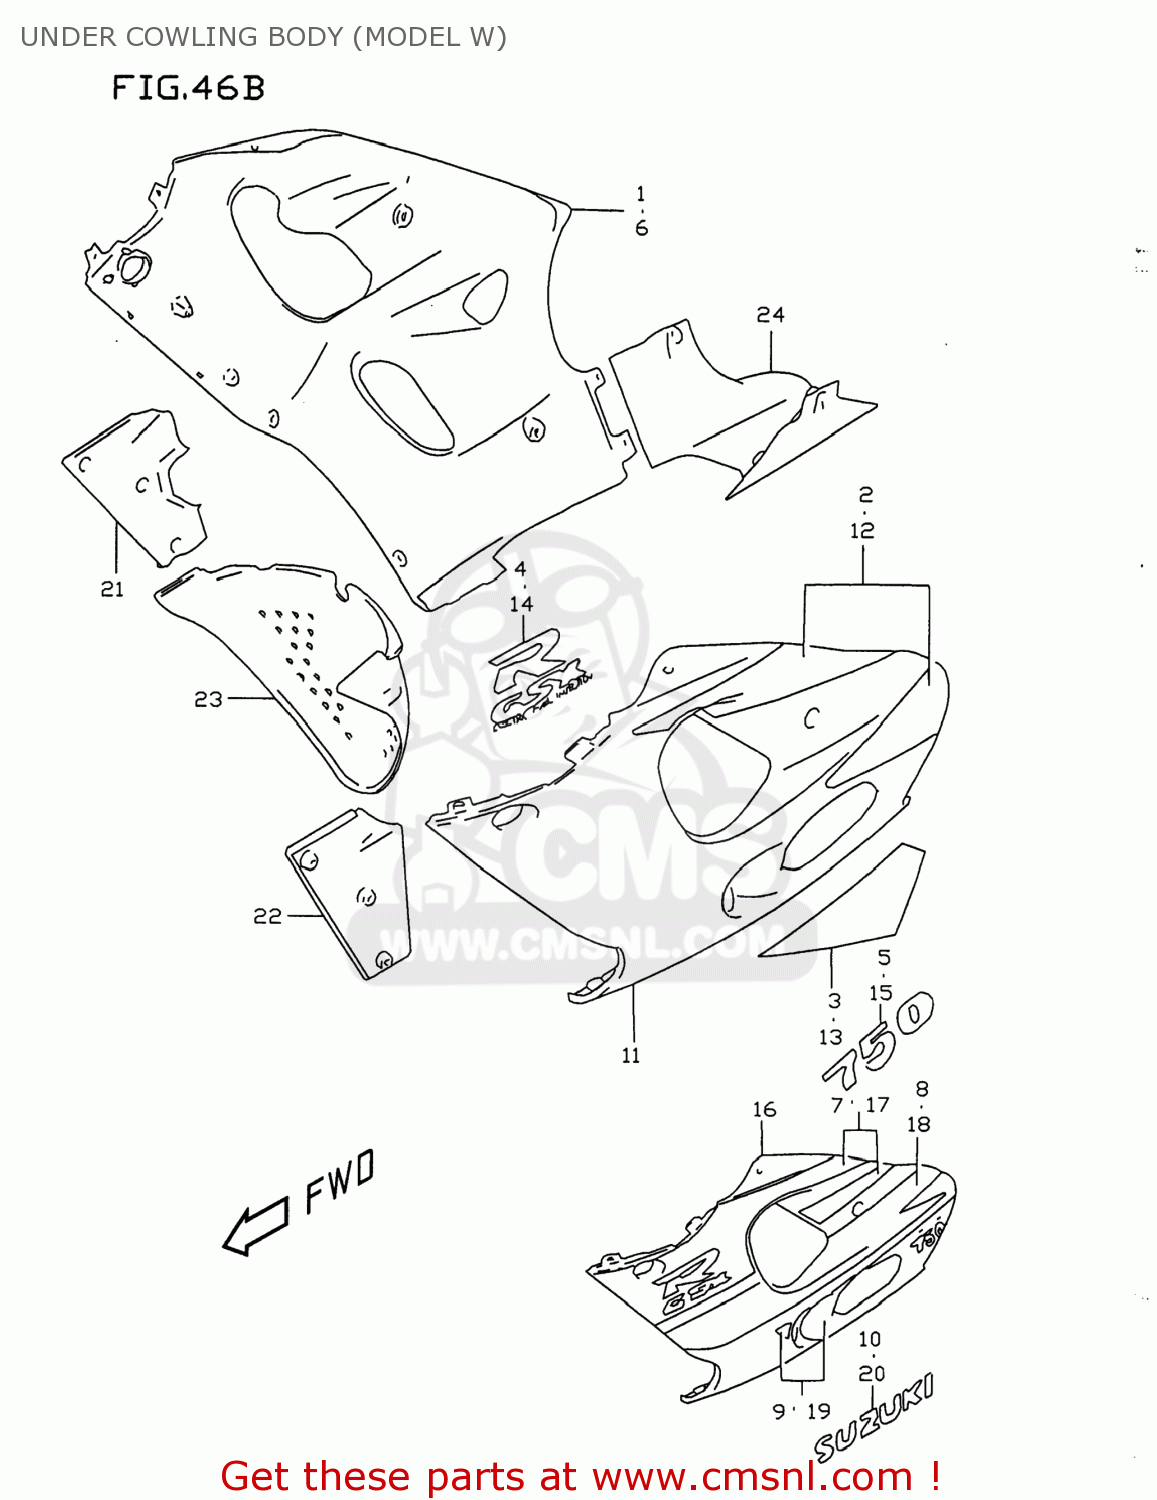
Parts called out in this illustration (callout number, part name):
1	COWLING ASSEMBLY,UNDER,RIGHT
2	TAPE SET,COWLING,UNDER
3	TAPE,COWL UNDER,R
4	EMBLEM,COWLING UNDER
5	EMBLEM,COWLING,UNDER
6	COWLING ASSEMBLY,UNDER,RIGHT
7	TAPE SET,COWL UNDER UPR,R
8	EMBLEM,COWLING UNDER
9	TAPE SET,COWL UNDER(750),R
10	EMBLEM,SUZUKI
11	COWLING ASSEMBLY,UNDER,LEFT
12	TAPE SET,COWLING,UNDER
13	TAPE,COWL UNDER,L
14	EMBLEM,COWLING UNDER
15	EMBLEM,COWLING,UNDER
16	COWLING ASSY,UNDER,L
17	TAPE SET,COWLING,UNDER,UPPER
18	TAPE SET,COWL UNDER,L
19	TAPE SET,COWL UNDER(750),L
20	EMBLEM,SUZUKI
21	COWLING,UNDER INNER,R
22	COWLING,UNDER INNER,L
23	COWLING,UNDER,CENTER
24	COWLING ASSEMBLY,UNDER,REAR
